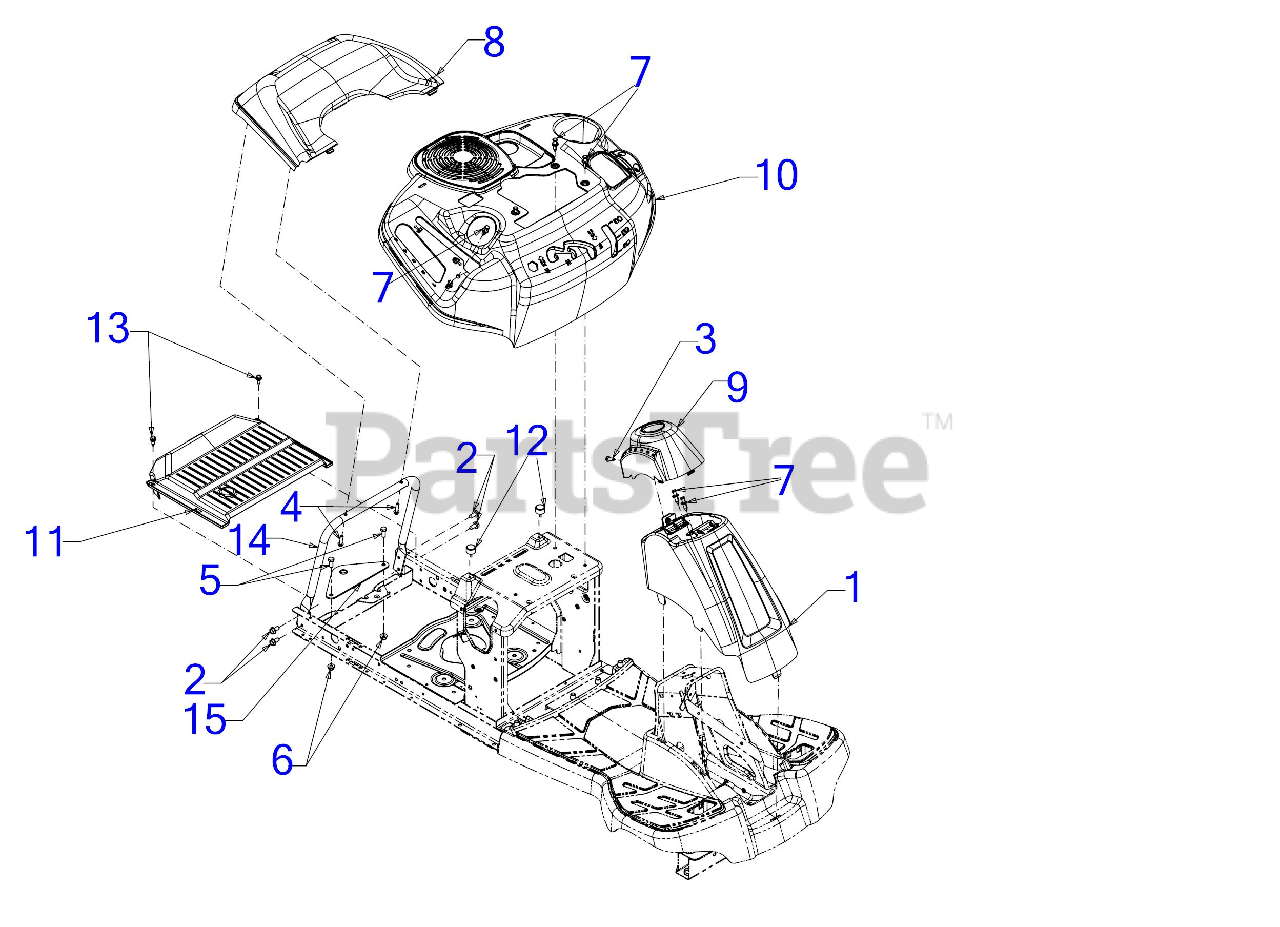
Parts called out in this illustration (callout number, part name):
1	COLUMN COVER ASSEMBLY (CUB)
2	SCREW 5/16-18 x .750
3	SCREW 1/4-20X.75
4	SCREW 1/4-15 x 1.00
5	SCREW 5/16-18 x .75 GR5
6	FLANGE LOCK NUT 5/16-18
7	PLASTIC RIVET
9	STEERING COLUMN CAP (CUB)
11	CVT DRIVE COVER
12	BUMPER .62 DIA x .50
13	SHOULDER SCREW
15	HITCH PLATE
